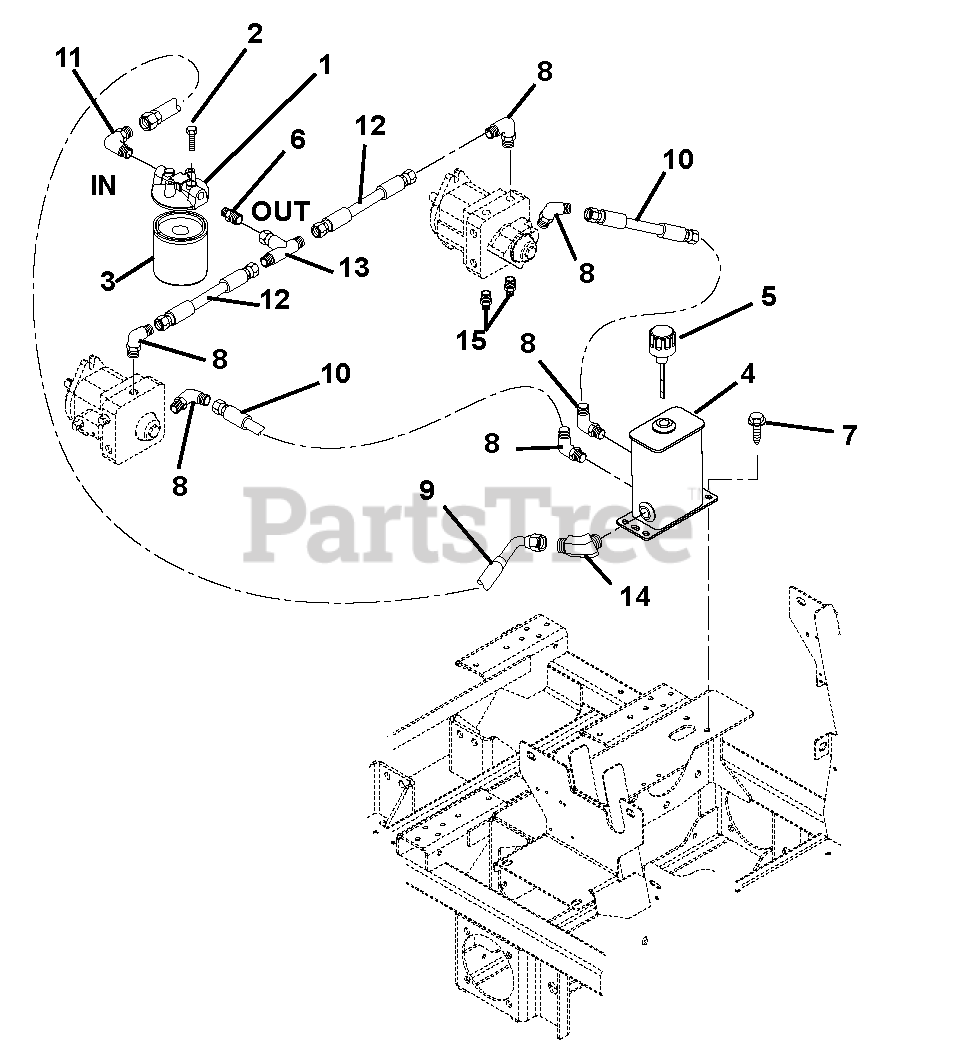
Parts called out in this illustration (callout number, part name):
1	Head, Filter
2	Bolt-Hex .25-20 x .50 Grade 5 Epoxy
3	Filter Element
4	Body, Hydraulic Tank
5	Breather, Dipstick
6	Fitting, Hydraulic, Straight
7	Screw-Tapping .38-16 x .75 Hex Washer Head
8	Fitting, Hydraulic, 90 Degree Elbow
9	Hose-Hydraulic Valve to Tank
10	Hose, Hydraulic, 10-inch
11	Fitting, Hydraulic, 90 Degree Elbow
12	Hose, Hydraulic .50, 5-Inch
13	Fitting, Hydraulic Tee
14	Fitting, Hydraulic 45 degree M8F-M80
15	Fitting, Hydraulic (4 F5OLO)
